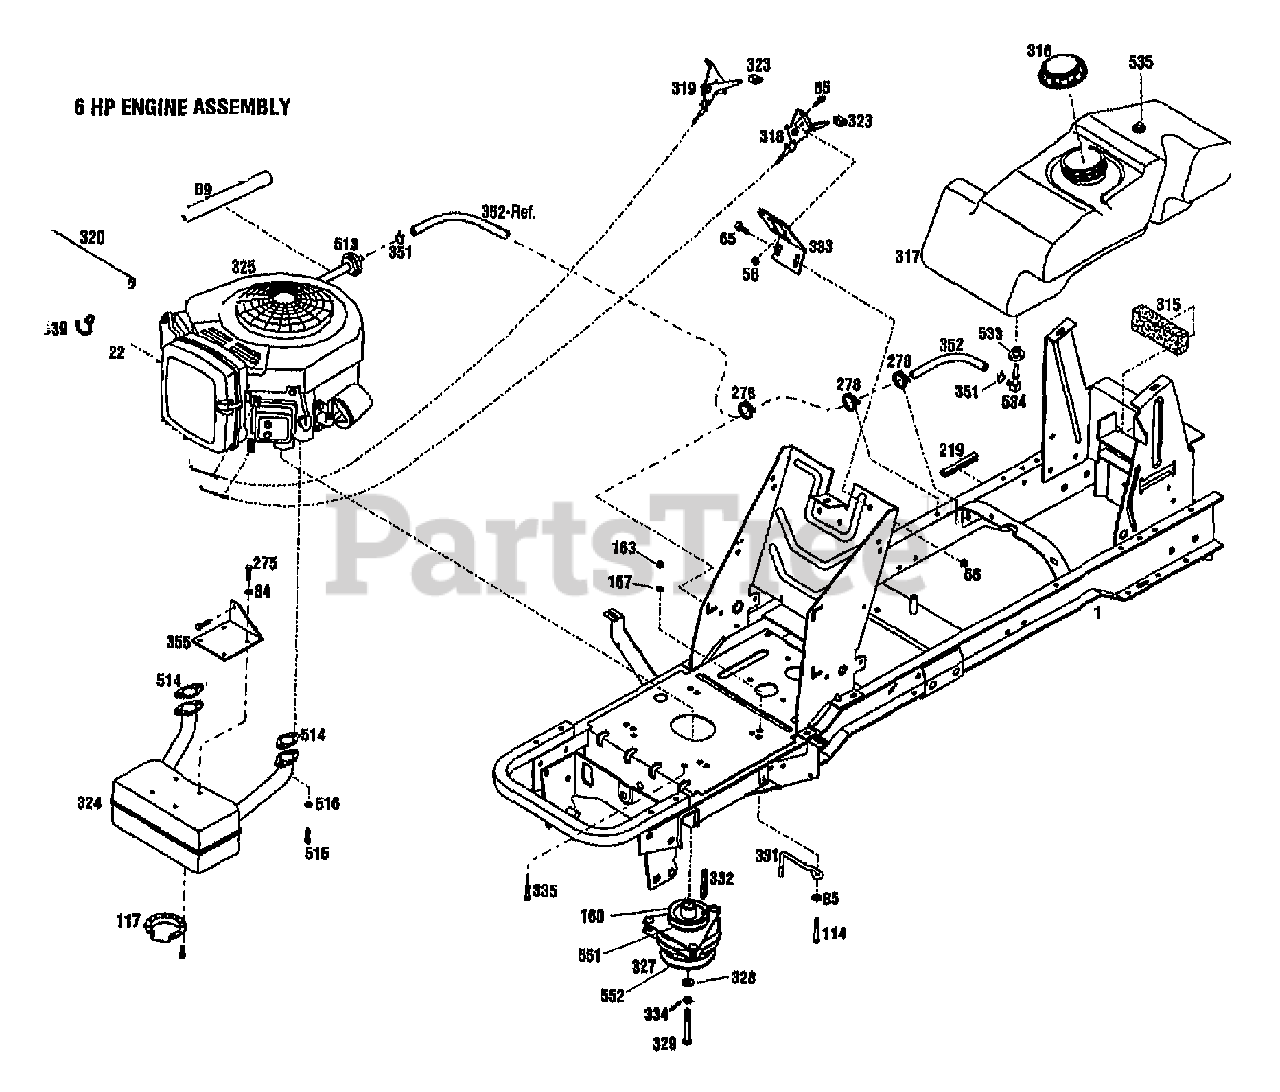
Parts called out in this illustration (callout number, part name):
56	NUT-HF/LK 1/4-20 ZP
65	SCR-HH 1/4-20X.625
84	WASHER-LK .25 ZP
85	WASHER-FLAT 3/8 SAE
89	INSULATION-FUEL LINE
114	SCR-THRD FRM 3/8-16X1.50
117	DEFLECTOR-MUFFLER
160	PULLEY-ENGINE
163	NUT-HEX 3/8-16 ZP
167	WASHER-LK .375 @ DEPL
275	SCR-HH 1/4-20X.625 G5 ZP
278	TIE-CABLE NYLON BLACK
315	PAD-FUEL TANK
316	CAP-FUEL
317	TANK-FUEL
318	CONTROL-CHOKE
319	THROTTLE-CONTROL
320	HOSE
322	ASSM-OIL VALVE
325	ENGINE, B&S 16HP MODEL 303777
327	CLUTCH-ELECTRIC
328	WASHER-SPEC 1.42X.468X.25 ZP
329	SCR-HH 7/16-20X3.00
331	CLUTCH-RETAINER
332	KEY-.25 SQ X 2.5
333	BRKT-MOUNTING CONTROL
334	WASHER-LK .438 ZP
335	SCR-HH 3/8-16X1.0 THDFM
351	CLAMP-HOSE
352	LINE-FUEL
355	BRKT-MUFFLER
513	FILTER-FUEL
514	MUFFLER GASKET
515	SCR-HH 1/4-20X1.0
516	WASHER-LK .25 ZP
533	BUSHING-RUBBER
534	ELBOW-90 DEG (FUEL LINE)
535	VENT-FUEL TANK
539	CAP-OIL DRAIN
551	BEARING-UPPER CLUTCH
552	BEARING-CLUTCH LOWER
